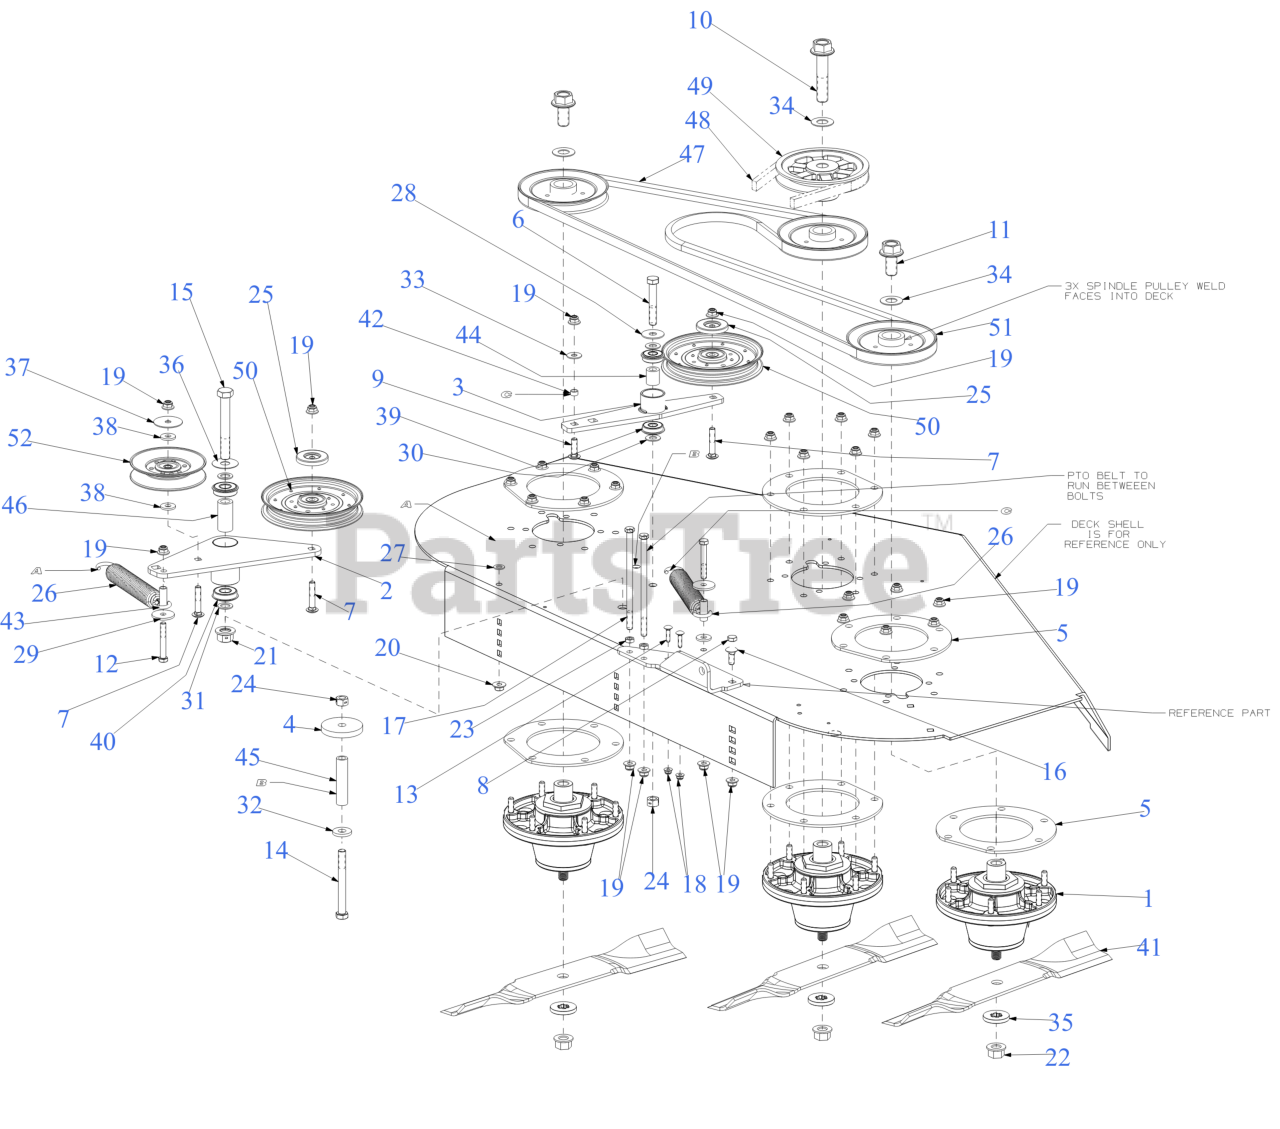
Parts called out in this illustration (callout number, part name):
1	SPINDLE ASSEMBLY
3	IDLER BRACKET
4	SPACER PLATE
5	SPINDLE SUPPORT BRACKET TOP/BTM
6	SCREW-HEX 1/2-13 x 3.00
7	CARRIAGE BOLT 3/8-16 x 2
8	SCREW 3/8-16 x 1 GR5
9	CARRIAGE BOLT 3/8-16 X1.25 GR5
10	CAP SCREW-HHFLG 3/4-10 X 3.50 GR8
11	CAP SCREW-HHFLG 3/4-10 X 1.50 GR8
12	HEX SCREW-3/8-16X2.5 GR5
13	SCREW 1/4-20 x 1 GR5
14	SCREW 1/2-13 x 4.5 GR 5
15	SCREW 5/8-18X4.5 GR5
16	CARRIAGE BOLT 3/8-16 x 1.00 GR5
17	SCREW 3/8-16 x 7.00 GR5
18	FLANGE LOCK NUT
20	FLANGE LOCK NUT
22	FLANGE NUT - 5/8-18 GDE 8
23	HEX JAM NUT 3/8-16 GR5
24	HEX NUT CTR LK 1/2-13
25	PULLEY CAP
26	SPRING 1.25" DIA x 8.5" LONG
27	FLAT WASHER
28	WASHER .51 x 1.5 x .07
29	FLAT WASHER .390x1.500x.134
30	FLAT WASHER .510 x .995
31	FLAT WASHER
32	FLAT WASHER .531 x 1.25 x .181
33	WASHER-.395 x 1.0 x .62
34	FLAT WASHER
35	FLAT WASHER - SPECIAL
36	THRUST WASHER .635x1.750x0.055
37	HUB CAP WASHER .406 x 1.92 x .060
38	FLAT WASHER .406ID X1.0 OD
39	ROLLER BEARING .5X1.37X.44
40	BALL BEARING W/RET
41	19" BLADE (HI LIFT)
41	Cub Cadet 54" HI LIFT BLADE SET
41	LOW-LIFT 19"BLADE (54"DECK)
41	BLADE- HI LIFT 19.0 XTREME
41	BLADE-19"MULCH 54"
41	19" XTREME BLADE
44	SPACER 0.51 x 0.88 x 1.00
46	SPACER 0.63 x 1.00 x 2.01
47	BELT-B SECTION 119.45"
48	V-BELT B SEC x 101.1
49	PULLEY-6.96 OD x .750 ID
50	IDLER PULLEY
51	SPINDLE PULLEY 6"
52	IDLER PULLEY 5.06 OD
